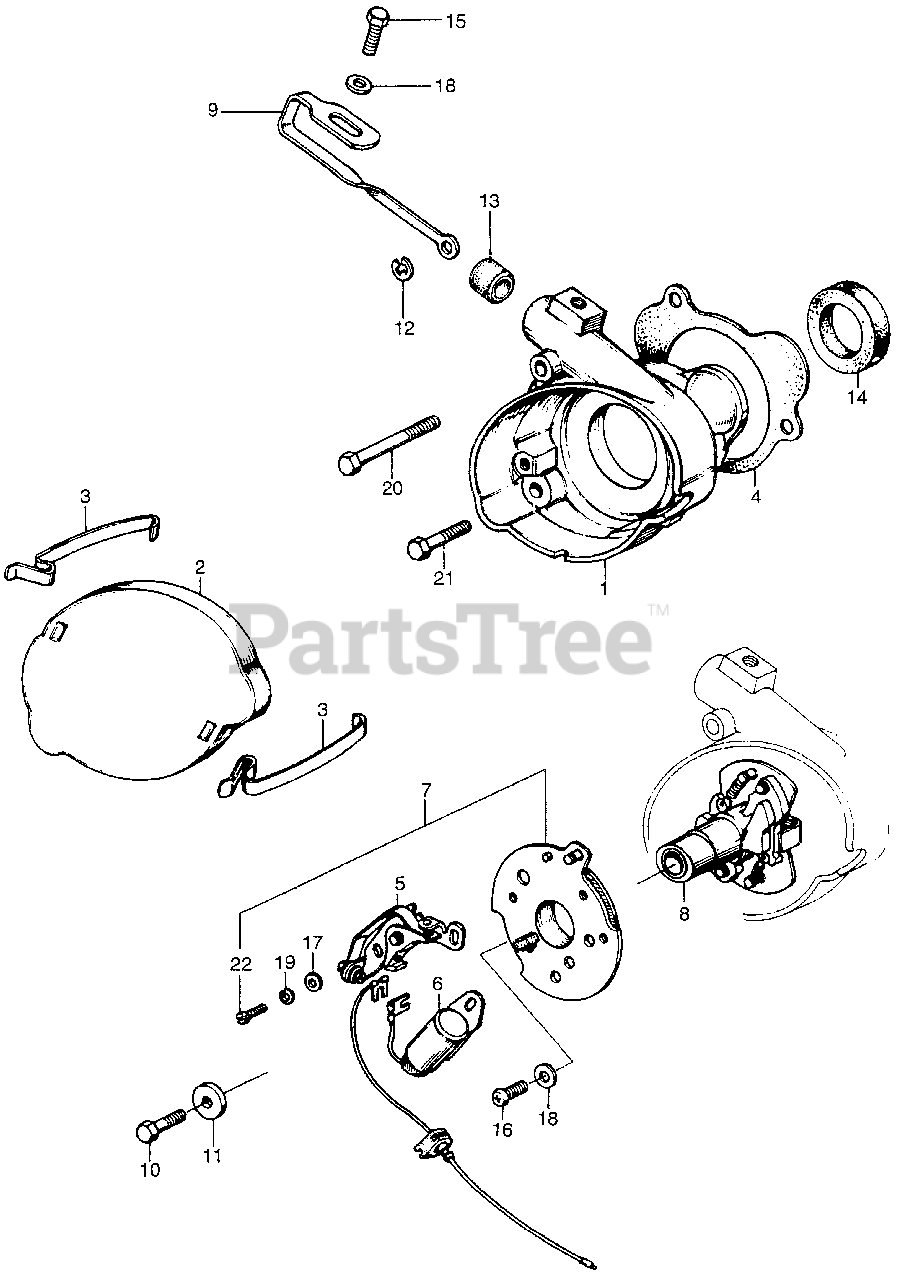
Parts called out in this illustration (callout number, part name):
1	CASE, BREAKER
2	CAP, BREAKER
3	CLAMP, BREAKER CAP (NOT AVAILABLE)
4	GASKET, BREAKER CASE
7	POINTS ASSY.
8	ADVANCER, SPARK (NOT AVAILABLE)
9	STOPPER, BASE POINTS
10	BOLT, SPECIAL (6X18)
11	WASHER, FLAT (6MM)
12	CLIP, ADVANCER ROD RETAINING
13	SEAL, COTTER (13.5MM) (NOT AVAILABLE)
14	OIL SEAL (22X36X6)
15	BOLT, HEX. (6X20)
16	SCREW, PAN (6X12)
17	WASHER, PLAIN (4MM)
18	WASHER, PLAIN (6MM)
19	WASHER, SPRING (4MM)
20	BOLT, FLANGE (6X50)
21	BOLT, FLANGE (6X28)
22	SCREW, HOLLOW PAN (4X5)
